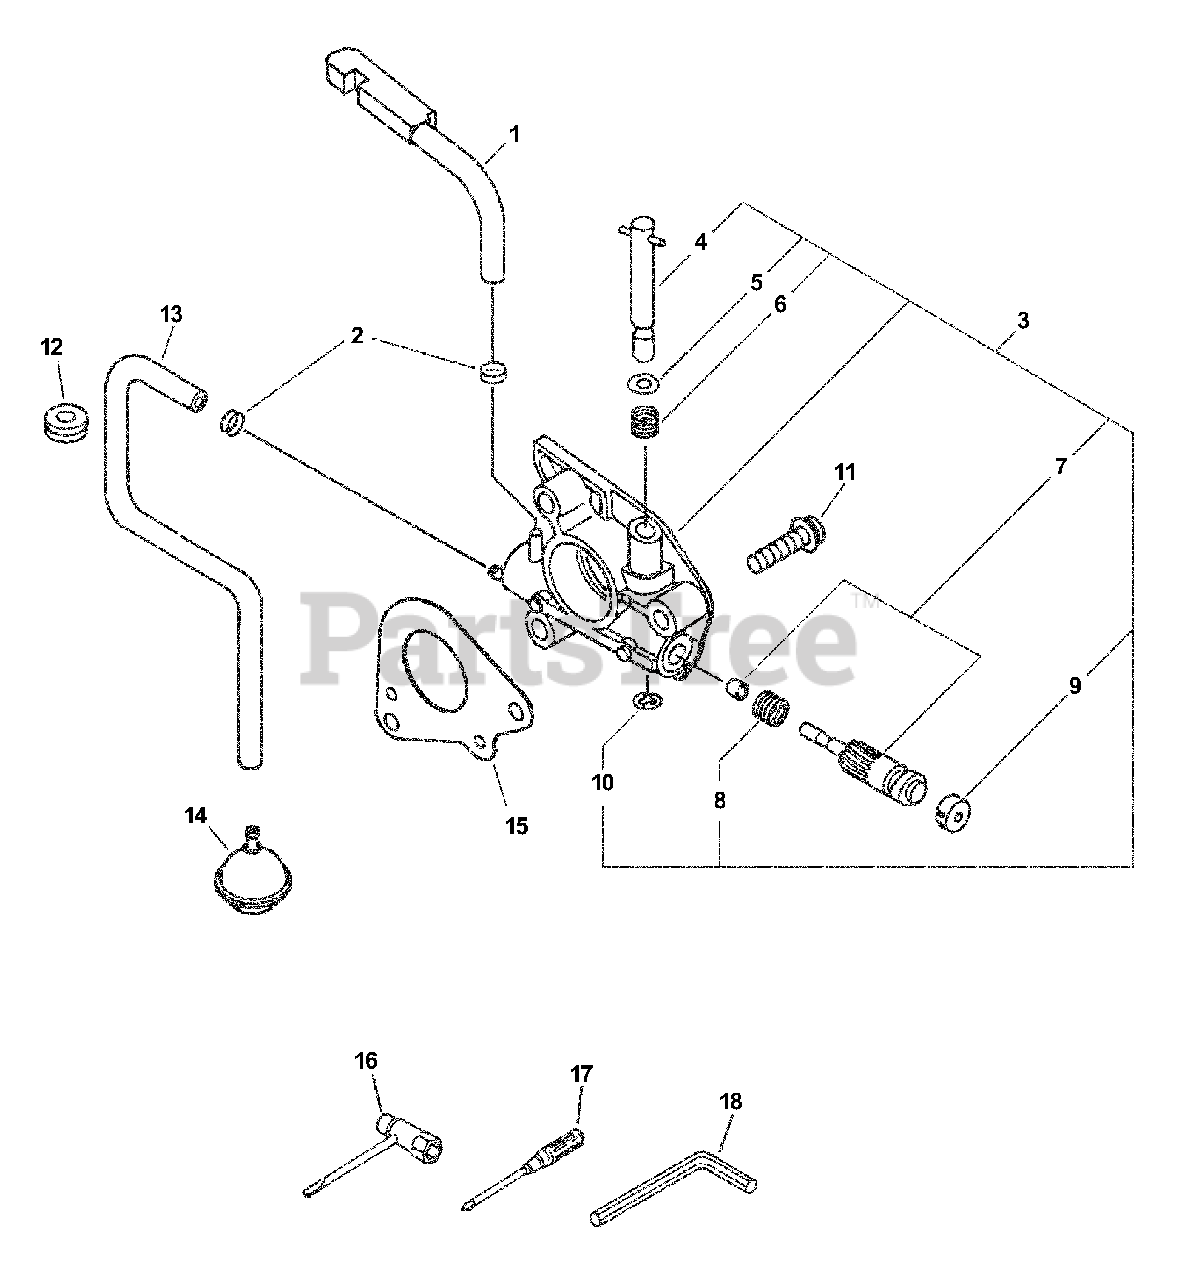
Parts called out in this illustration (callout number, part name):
1	PIPE, OIL OUTLET
2	CLIP Ø6.5 MM
3	AUTO-OILER ASSY
4	SCREW, ADJUSTER
7	PLUNGER ASSY
9	CAP, OIL PUMP
11	SCREW 4×16
13	PIPE, OIL
14	FILTER, OIL
15	PLATE, SEAL
16	T-WRENCH 13×19×180
17	SCREWDRIVER, PHILLIPS
18	WRENCH, ALLEN 4 MM
